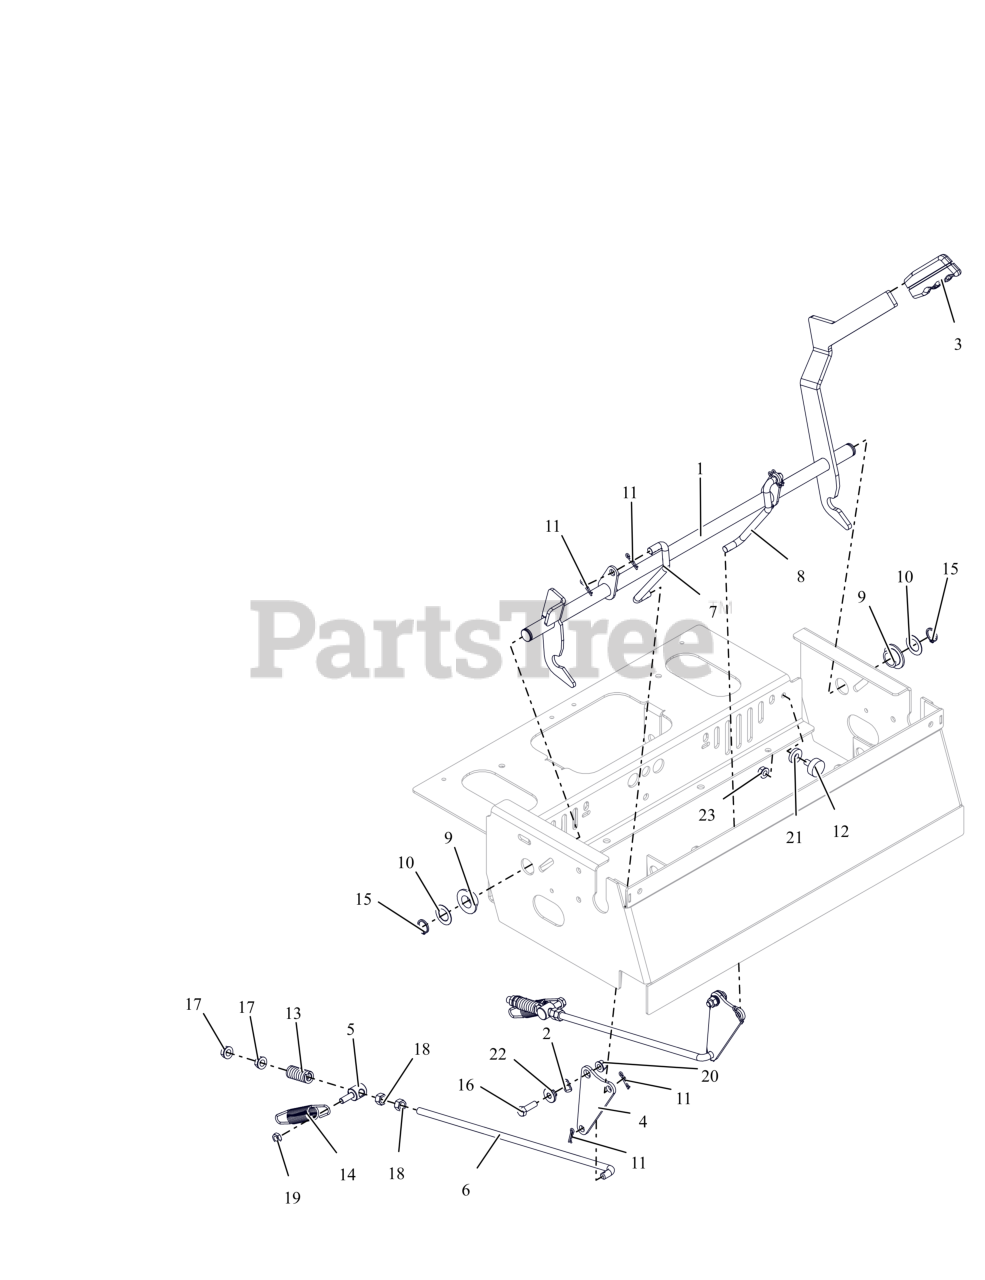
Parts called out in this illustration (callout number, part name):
1	WLDMT, PT200/400 PARK BRAKE
2	WAVE WASHER .531X.781X.125FH
3	GRIP, PARKING BRAKE (YELLOW)
4	PLATE, BRAKE PIVOT
5	TRUNNION, .38-16
6	ROD, BRAKE ADJ.
7	LINKAGE, RH BRAKE ACTUATING
8	LINKAGE, LH BRAKE ACTUATING
9	BSHG-FLG .762X1.48X.44 NYL
10	WSHR-HDND-THRST .758X1.23X.031
11	PIN, HAIR #225 .072X1.09
12	BUMPER, RUBBER
13	SG-COMP .142 X .710 X 1.75
14	SPRING-TENS .105X.850X.4.880
15	RG-RTNG-EXT .689X.078
16	BLT,HEX .31-18X1.00 G5 ZCC
17	NUT, SPNLK-FLG .38-16 G5 ZCC
18	NUT-STD .375-16 G2 ZCC
19	NUT-LK-CTR-JAM .312-18 GB ZCC
20	NUT-LK-TOP-FLG .312-18 GF ZCC
21	WSHR, FLT .328X.870X.179 ZCC
22	BSHG-FLG .32X.500X.344X.880
23	NUT,SPNLK-FLG .31-18 G5 ZCC
